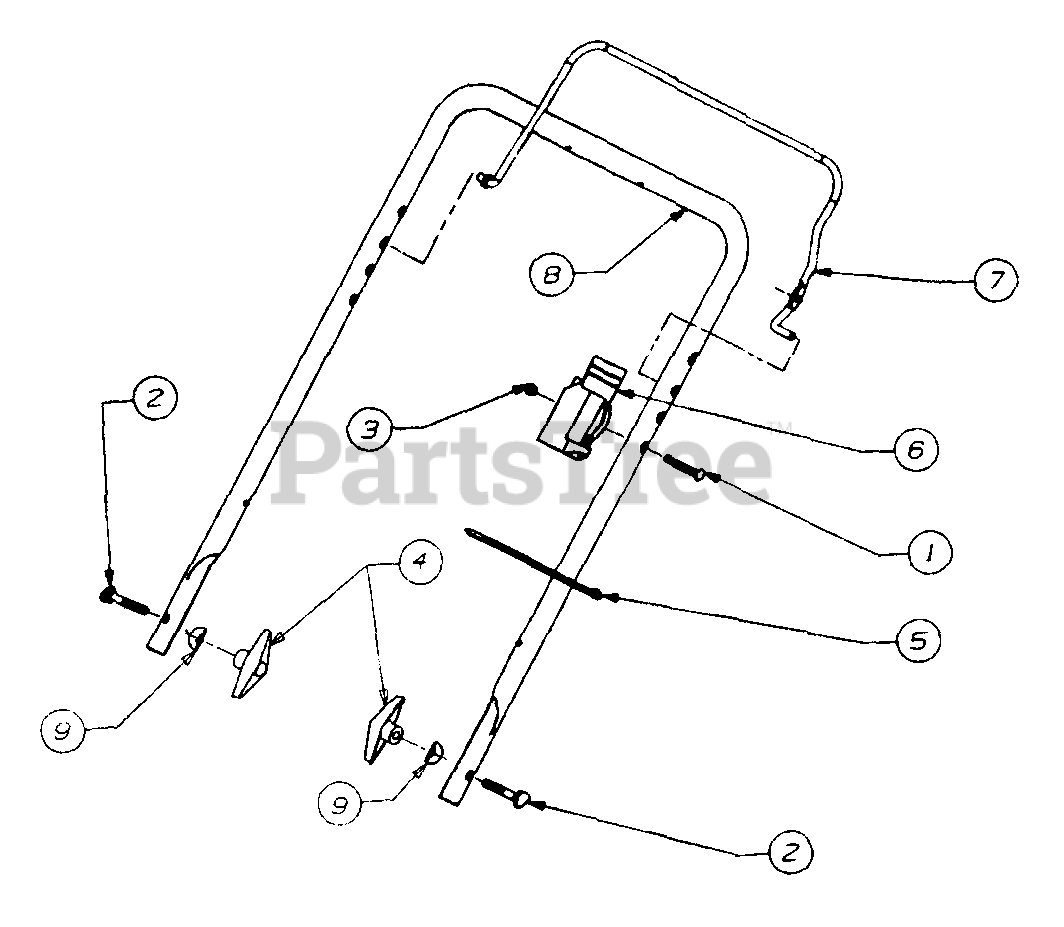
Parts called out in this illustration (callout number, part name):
1	Screw - Oval C-Sink L
2	Bolt Carriage
3	Nut Insl. Lock
4	Knob - Handle
5	Tie Cable
6	Body - Lever Control
